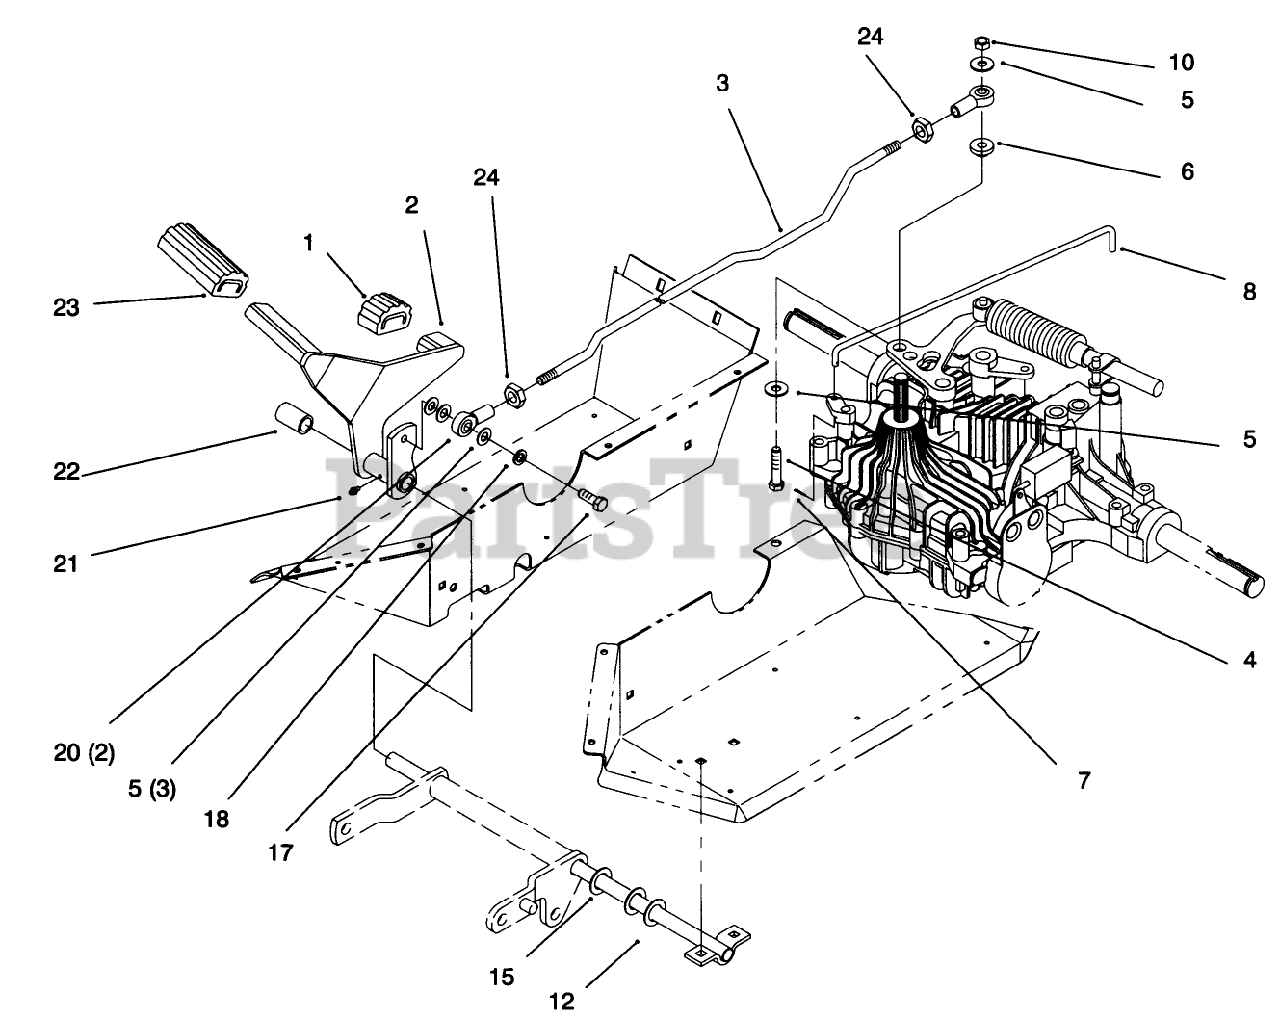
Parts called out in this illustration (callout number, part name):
1	PAD-PEDAL
3	ROD - HYDRO
4	SCREW-HH
5	WASHER-FLAT
6	BUSHING
7	PIN-COTTER
10	NUT-LOCK, NI
12	WASHER-FLAT
15	SPACER
17	SCREW-HH
18	WASHER-LOCK
20	END-ROD, FEMALE
21	FITTING-GREASE
22	SPACER
24	NUT-HJ
